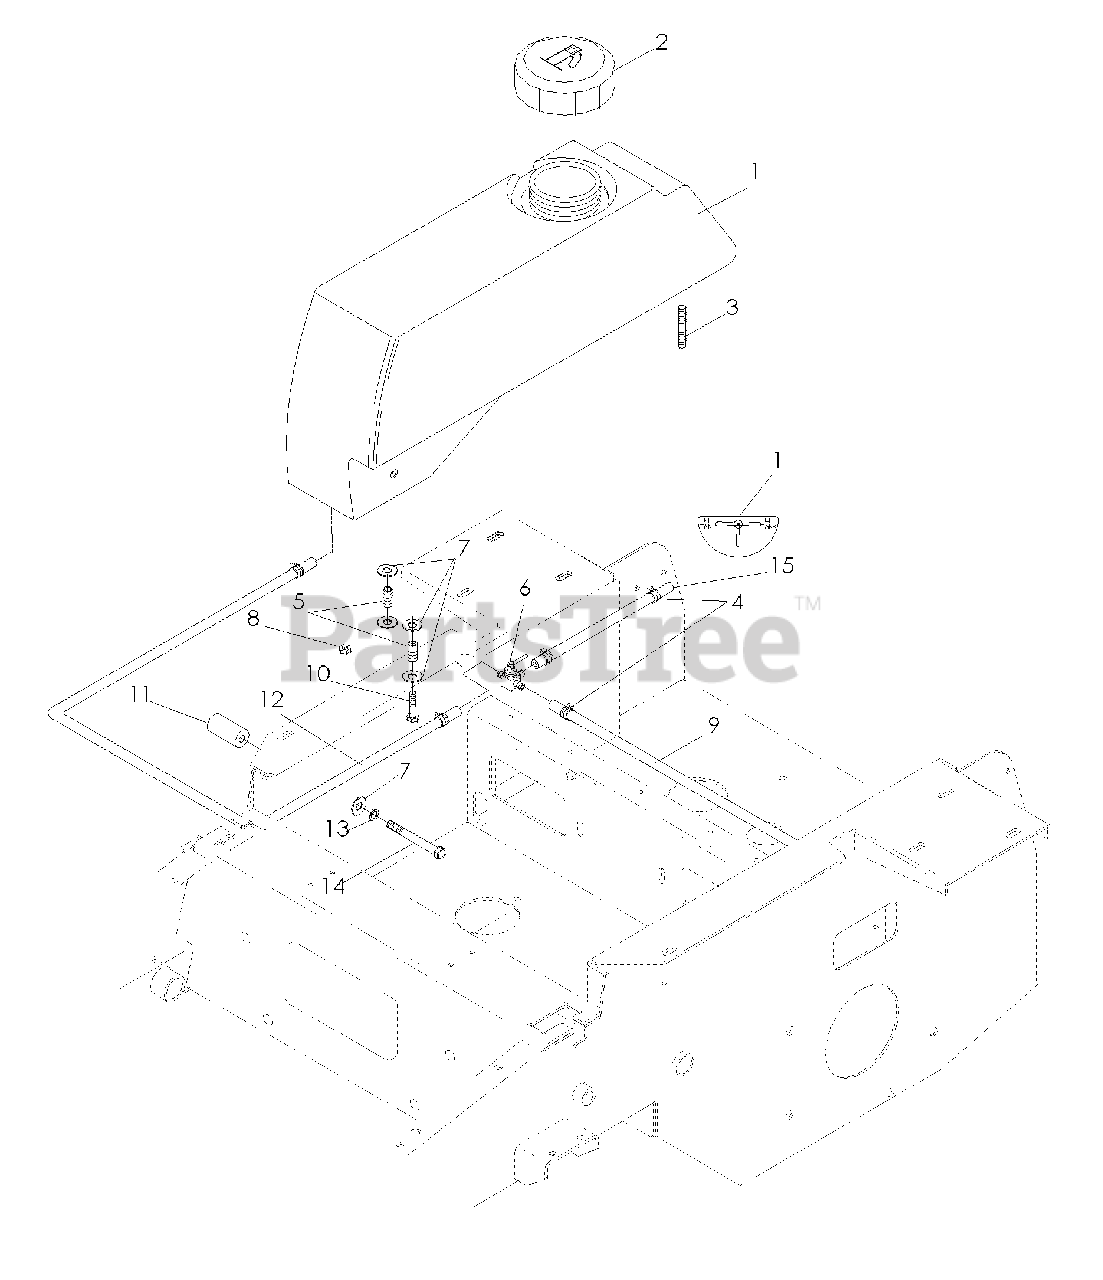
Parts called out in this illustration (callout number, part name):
1	FUEL TANK RT
1	FUEL TANK LT
2	FUEL CAP
4	HOSE CLAMP
6	FUEL VALVE
7	WASHER 5/16 STD FLT
8	NUT 5/16-18 CENTERLOCK
10	HCS 5/16-18 x 1
11	TANK SP ACER
13	WASHER 5/16 LOCK
14	HCS 5/16-18 x 4
16	DECAL, FUEL LINE
